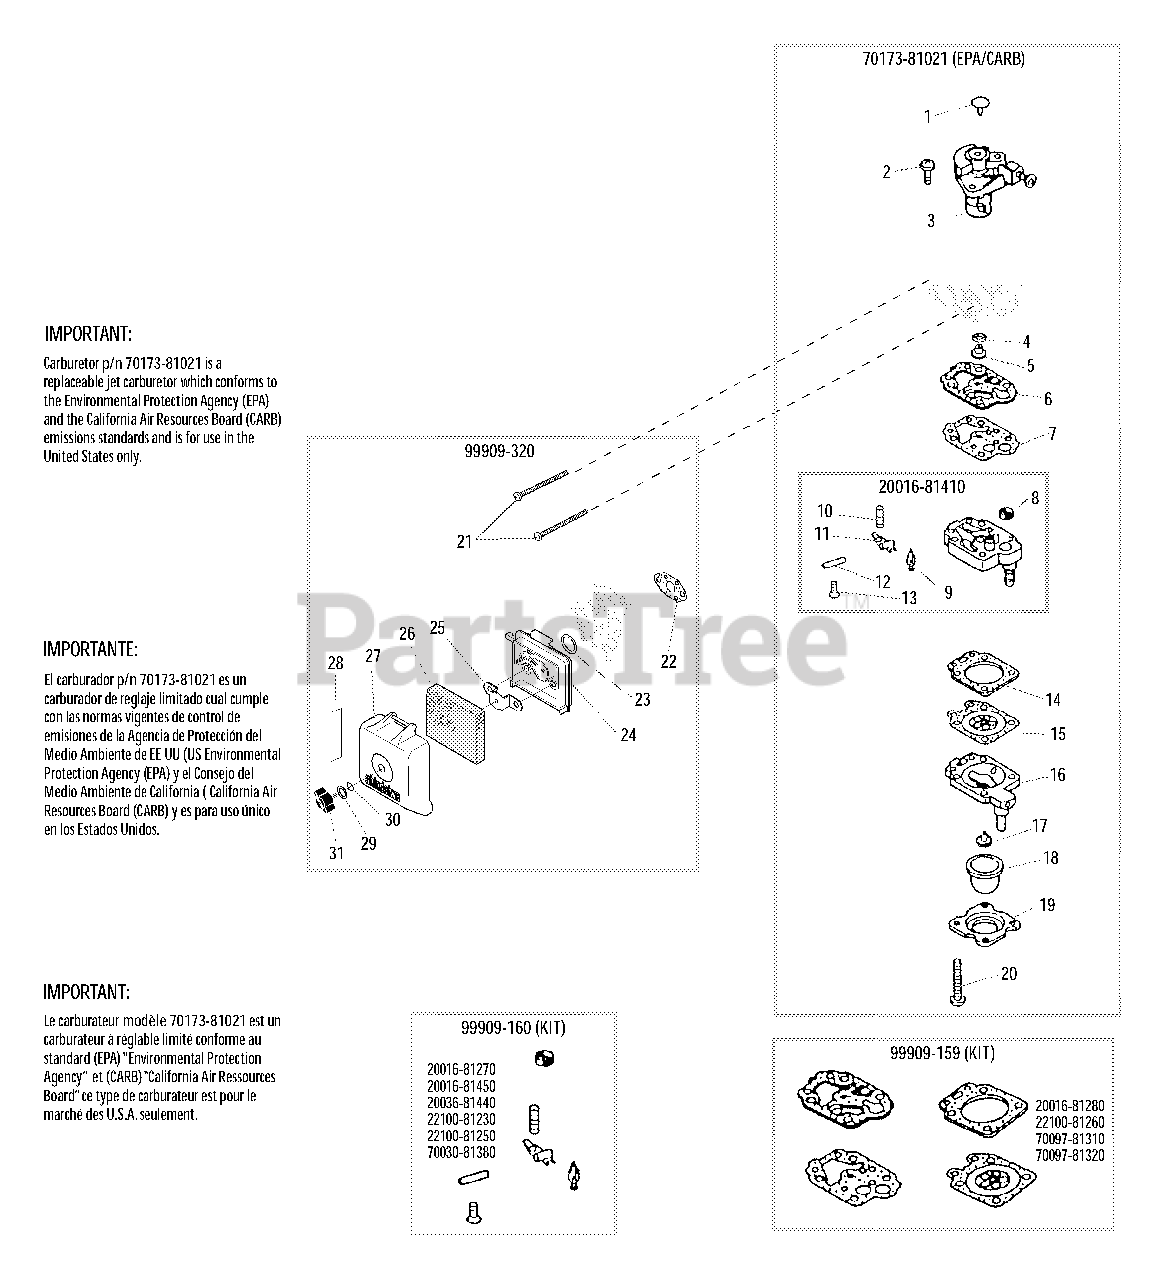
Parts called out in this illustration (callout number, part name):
1	PLUG
2	SCREW, THROTTLE COLLAR
3	THROTTLE VALVE ASSY
4	O-RING
5	MAIN JET - #38
6	GASKET, PUMP
7	DIAPHRAGM, PUMP
8	SCREEN, FUEL INLET
9	VALVE, INLET NEEDLE
10	SPRING, METERING LEVER
11	LEVER, METERING
12	PIN, METERING LEVER
13	SCREW
14	GASKET, METERING DIAPHRAGM
15	DIAPHRAGM, METERING
16	BODY ASSY, PURGE
17	VALVE, CHECK
18	BULB, PURGE
19	RETAINER, PURGE BULB
20	SCREW
21	SCREW - 5×67
22	GASKET, CARBURETOR
23	O-RING 15
24	CASE, AIR FILTER
25	BRACKET
26	FILTER, AIR
27	COVER, AIR FILTER
28	LABEL, CHOKE
29	WASHER, CONE M6
30	O-RING
31	THUMBSCREW
20016-81410	BODY ASSY, PUMP
70173-81021	CARBURETOR
99909-159	GASKET / DIAPHRAGM KIT
99909-160	VALVE KIT, INLET NEEDLE
99909-320	AIR FILTER ASSY
